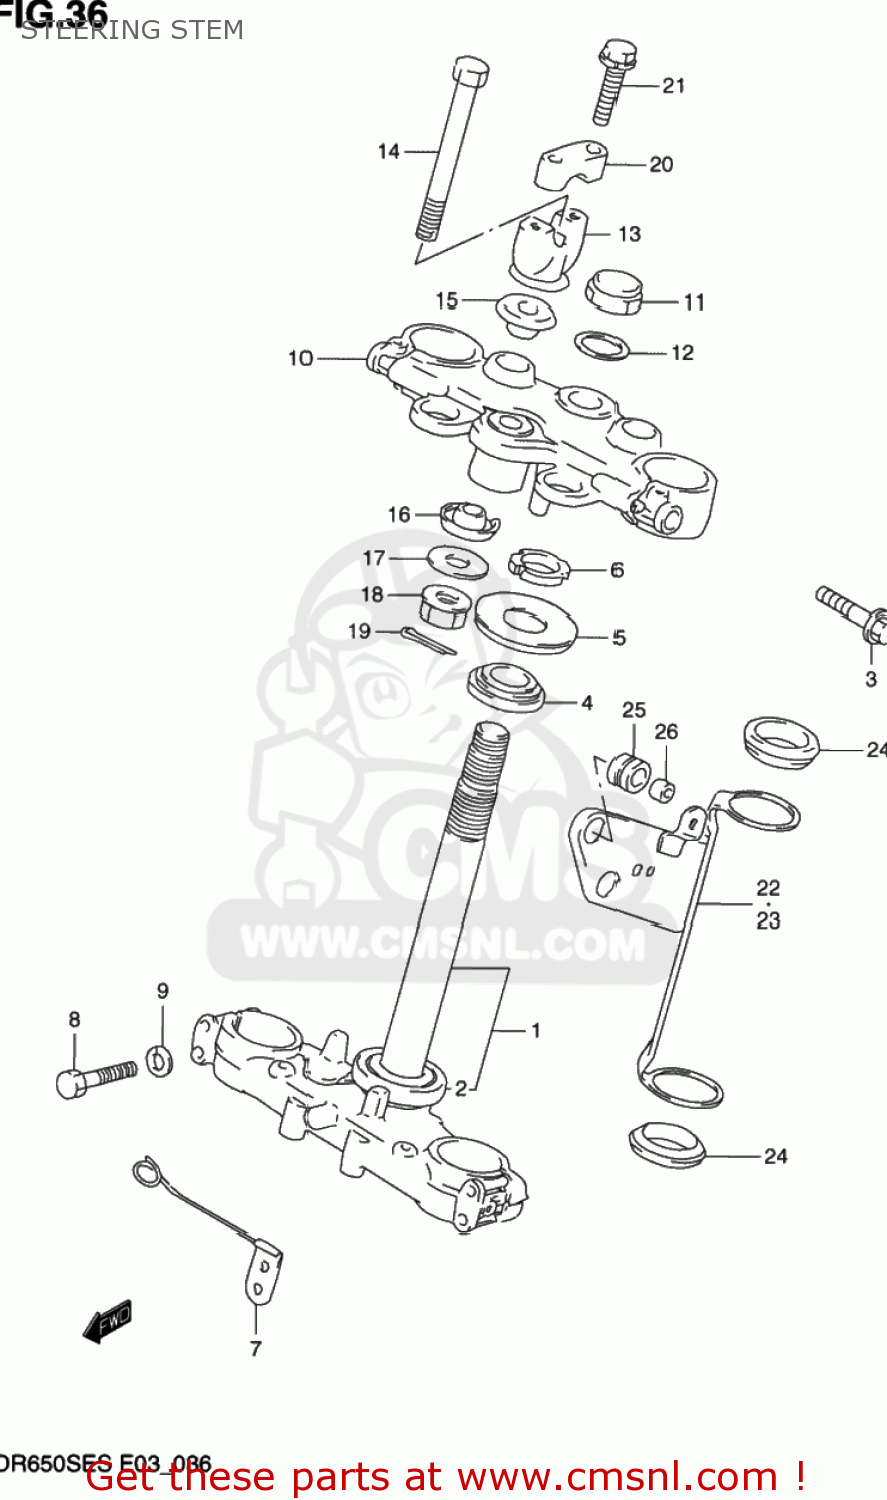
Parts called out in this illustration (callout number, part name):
1	STEM,STEERING
2	BEARING(30X55X17)
3	BOLT
4	TAPER,ROLLER BEARING
5	SEAL,STEERING UPR DUST
6	NUT,STEERING STEM
7	GUIDE, SPEEDOMETER CABLE
8	BOLT
9	WASHER,LOCK
10	HEAD,STEERING STEM
11	NUT,CAP
12	WASHER(22.5X32X1.6)
13	HOLDER,HANDLE LWR
14	BOLT
15	DAMPER,UPR
16	DAMPER,LWR
17	WASHER,HANDLEBAR HOLDER
18	NUT
19	COTTER PIN
20	HOLDER,HANDLE UPR
21	BOLT
22	COVER,FORK,R
23	COVER,FORK,L
24	CUSHION,HEADLAMP BRACKET
25	CUSHION
26	SPACER (6.8X10X10)
